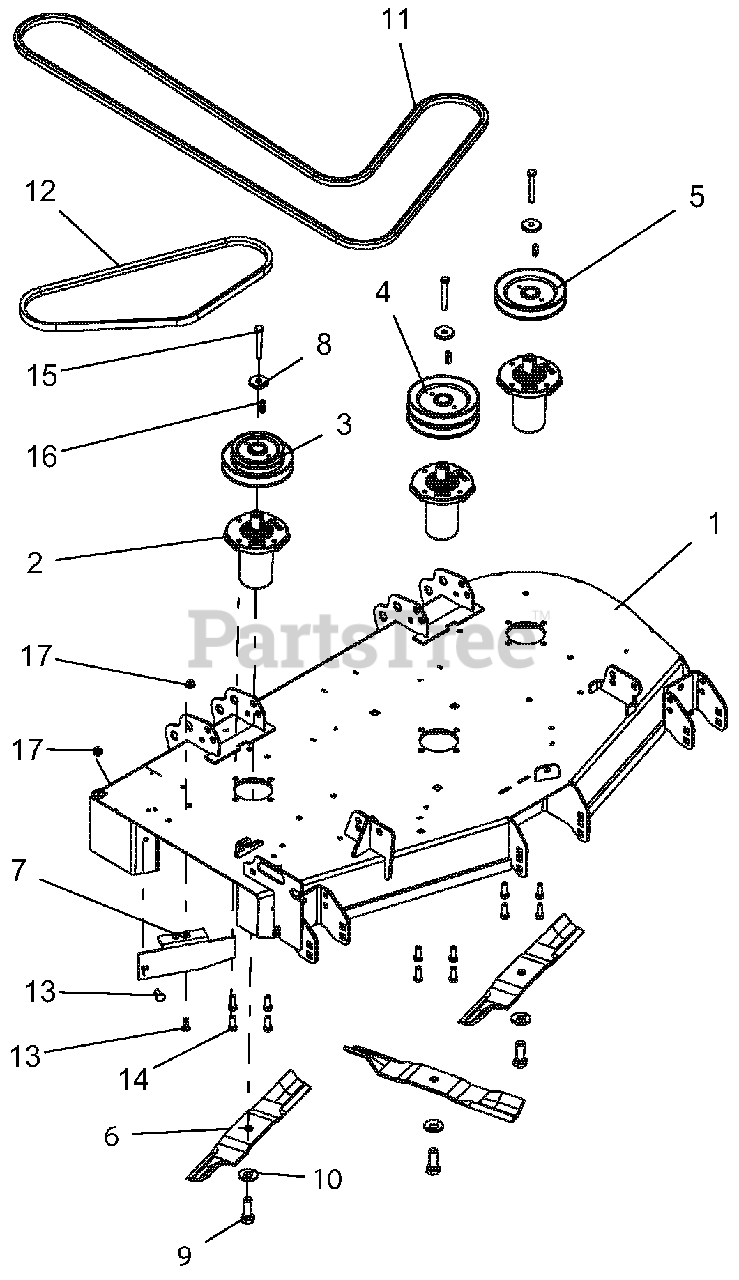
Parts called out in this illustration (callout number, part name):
1	KIT, DECK-48' W/SAFETY DECALS-RED
2	SERVICE, ASM SPINDLE- DUCTILE
3	PULLEY, DOUBLE -1" ID X 5.75" & 4.25" OD
4	PULLEY, DOUBLE-1" ID X 5.75" OD-BLACK
5	PULLEY, V - 1" ID X 5.75" OD-BLACK
6	BLADE, 16.19" MOWER (HI-LIFT)
7	BAFFLE, DISCHARGE, 44"-48"-RED
8	RETAINER, SHEAVE SPINDLE
9	BLT, HEX .62-18X1.75 GR8 YWZC
10	WSHR, BLVL .63X1.625X.14
11	BELT, BB 118.00 WRAPPED HEX
12	V-BELT, B-RAW EDGE COGGED
13	BLT-RDHDSQSHNK .31-18X1.00 G5 Y
14	BLT-HEX .38-16X1.00 GR5 YWZC EP30
15	BLT-HEX .38-16X2.75 GR8 YWZC
16	KEY-SQ .250X.250X1.00 RC 40-50
17	NUT-LK-NYL-FLG .31-18 YWZC
